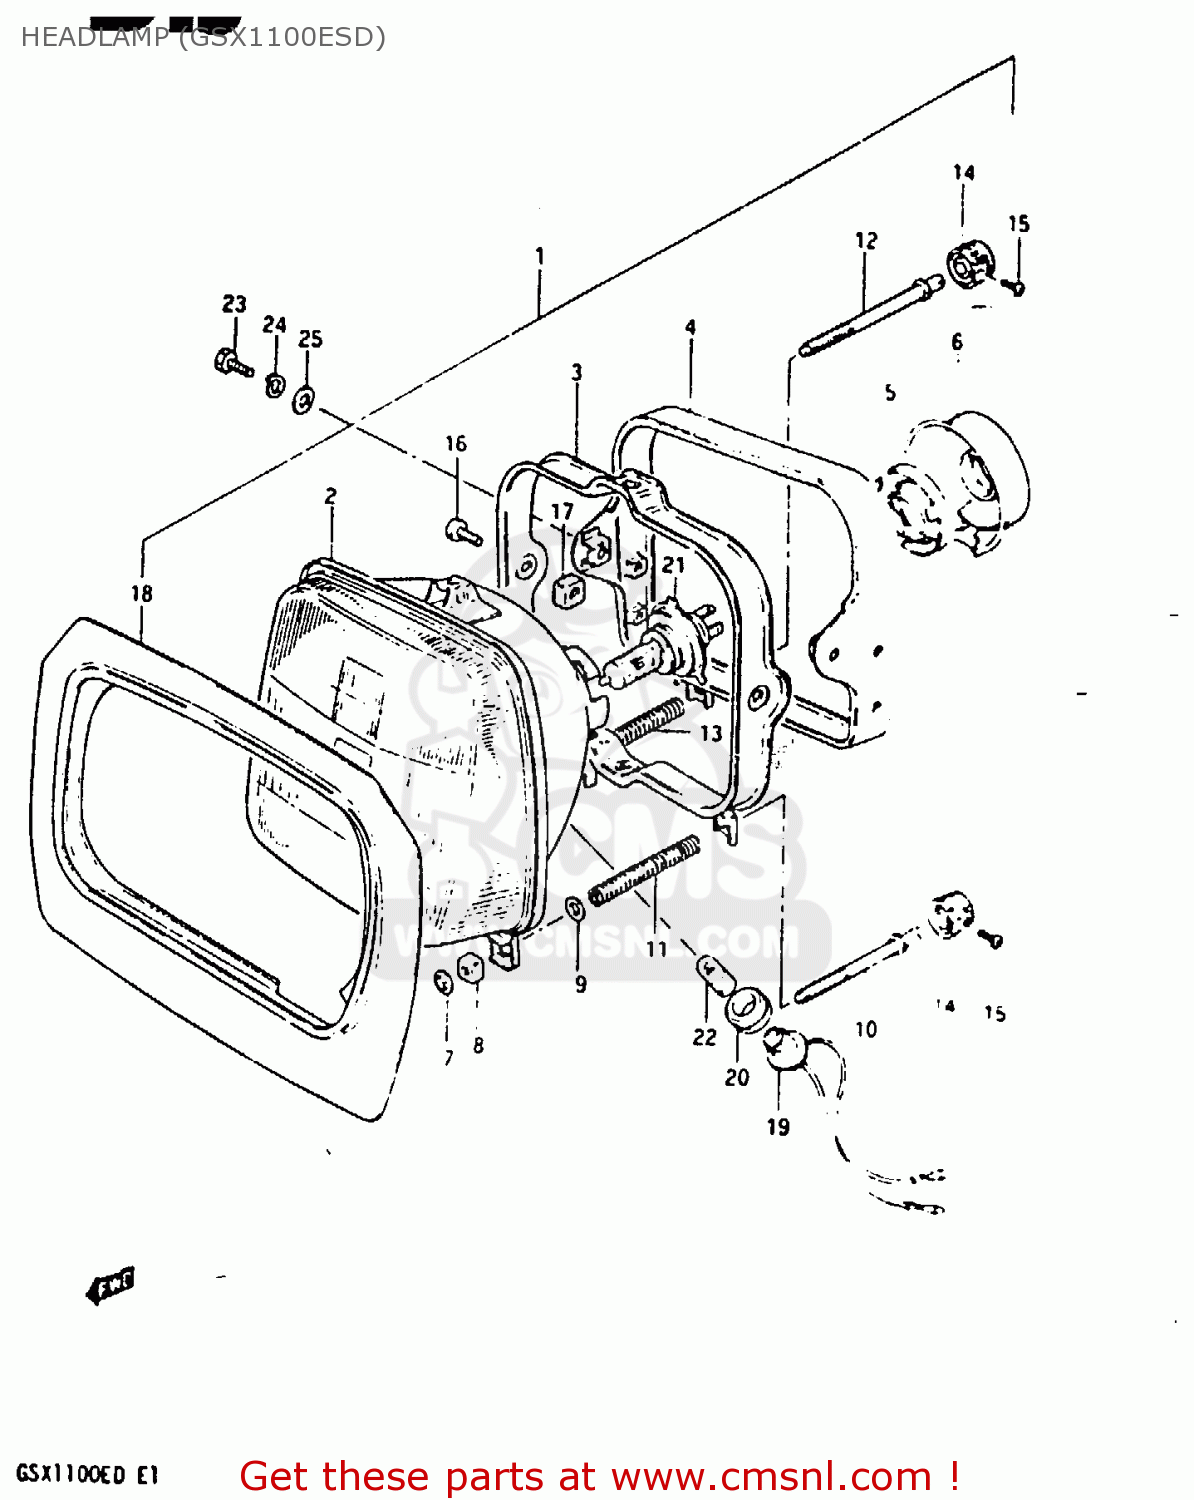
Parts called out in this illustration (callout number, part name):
1	HEADLAMP ASSY
2	UNIT
3	RING,MOUNTING
4	HOUSING,LAMP UNIT
5	HOLDER
6	COVER,HEADLAMP SOCKET
7	NUT,HEADLAMP ADJUSTER
8	NUT,HEADLAMP ADJUSTER
9	WASHER
10	SCREW,HEADLAMP ADJUST
11	SPRING
12	SCREW,ADJUSTING
13	SPRING
14	KNOB,ADJUSTER
15	SCREW
16	SCREW
17	NUT
18	SHADE
19	SOCKET
20	JOINT,RUBBER
21	BULB(12V60/55W,H4)
22	BULB(12V4W)
23	BOLT
24	LOCK WASHER
25	WASHER
